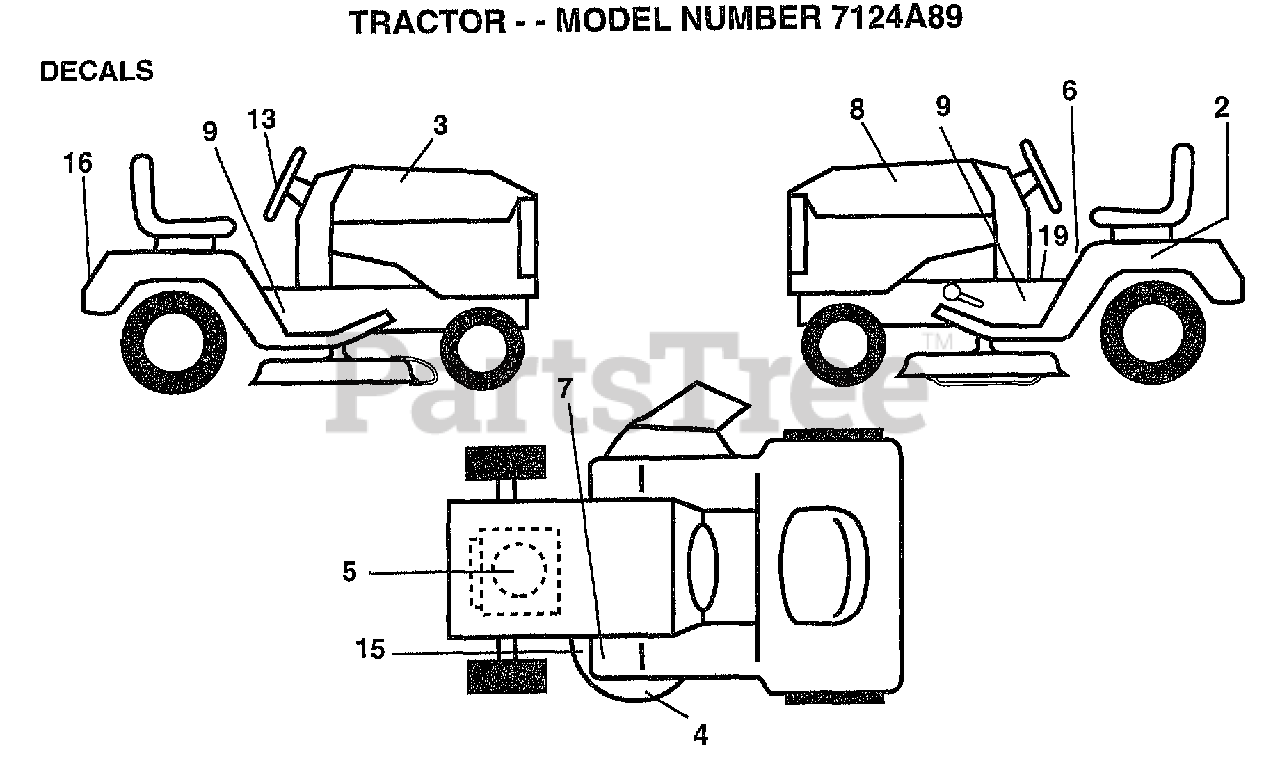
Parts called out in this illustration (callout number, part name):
2	DECAL.BATRY.3-3908
3	DECAL.HOOD.RH
4	DECAL DECK WIZ +
5	DECAL, HP ENGINE
6	"DECAL DANGER,FEND"
8	DECAL.HOOD.LH
9	DECAL CHASSIS
13	DECAL.INS.STRG.WL
15	DECAL
19	"DECAL DASH,OPER."
